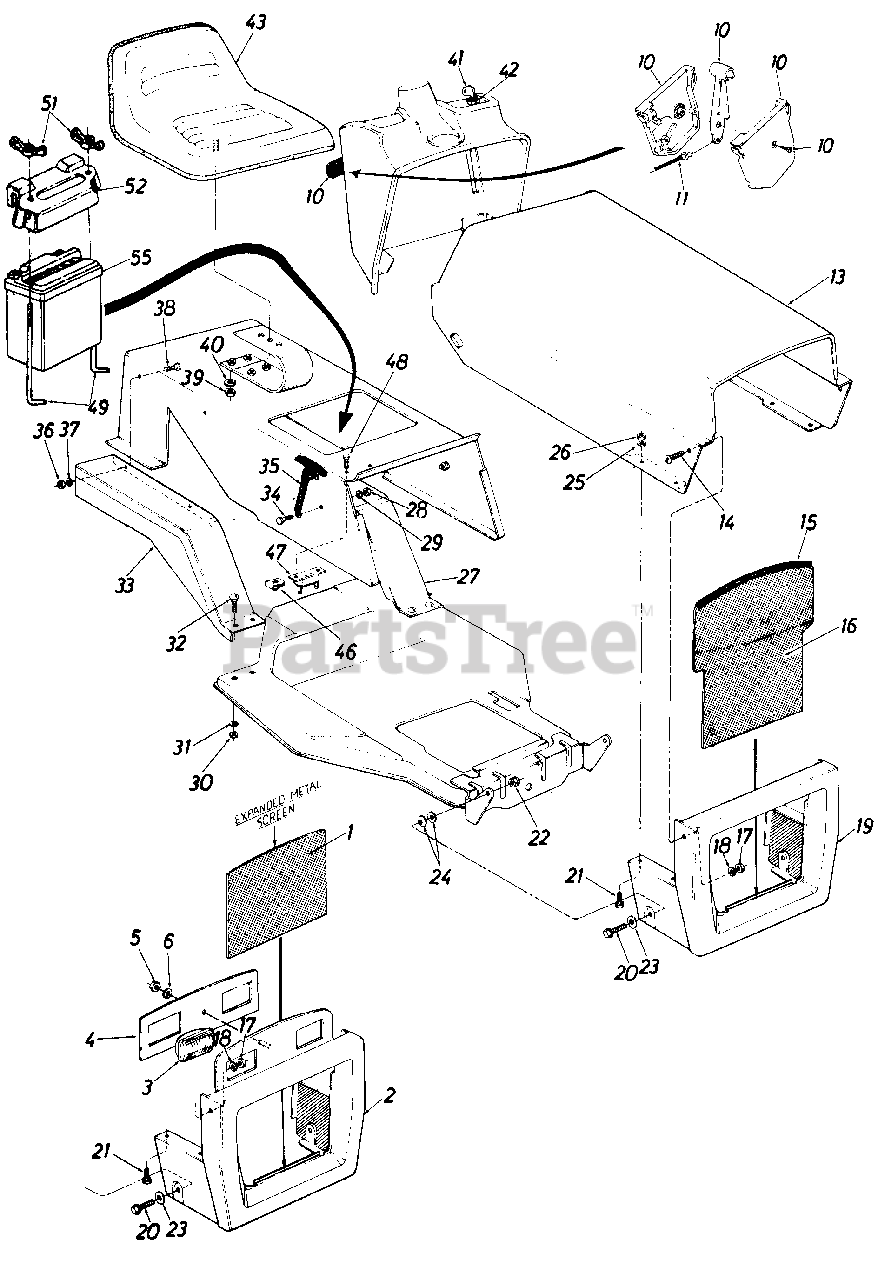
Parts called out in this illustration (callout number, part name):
1	Screen-Grille
2	Grille Ass'y.
3	Head Light
4	Head Light Retainer
5	Hex Nut #10-24 Thd.
6	L-Wash. #10 I.D.
10	Throttle Control Box Ass'y.
11	Throttle Control Wire
13	Hood-Front
14	Truss Hd. Mach. Scr. 1/4-20 x.50" Lg.
15	Extruded "U"-Channel 22.50" Lg.
16	Screen-Grille
17	Hex Nut 1/4-20 Thd.
18	L-Wash. 1/4" Scr.
19	Grille Ass'y.
20	Hex Scr. 3/8-16 x 1.00" Lg.
21	Hex Sems Scr. 1/4-20 x .75" Lg.
22	Hex Cent. L-Nut 3/8-16 Thd.
23	Fl-Wash. .385 I.D. x .620 O.D. x .063
24	Bell-Wash. .400 I.D. x .88 O.D.
25	L-Wash. 1/4" Scr.
26	Hex Nut 1/4 -20 Thd.
27	Fender Ass'y. L.H.
28	Hex Nut 1/4-20 Thd.
29	L-Wash. 1/4" Scr.
30	Hex Nut 1/4-20 Thd.
31	L-Wash. 1/4" Scr.
32	Carriage Bolt 1/4-20 x .62" Lg.*
33	Fender Ass'y. R.H.
34	Hex Scr. 1/4-20 x .62" Lg.
35	Hood Lock Ass'y.
36	Hex Nut 10-24 Thd.
37	Wash. #10 Scr. Ext.
38	Truss Hd. Mach. Scr. 10-24 x.62" Lg.
39	Hex Nut 1/2-13 Thd.
40	L-Wash. 1/2" Scr.
41	Ignition Key
42	Ignition Switch
43	Seat Ass'y.-Comp.
46	Speed Nut 10-24
47	Circuit Breaker
48	Truss Hd. Mach. Scr. #10-14 x.62" Lg.
49	Hold-Down Rod
51	Wing Nut 1/4-20 Thd.
52	Battery Cover
55	12V Battery
